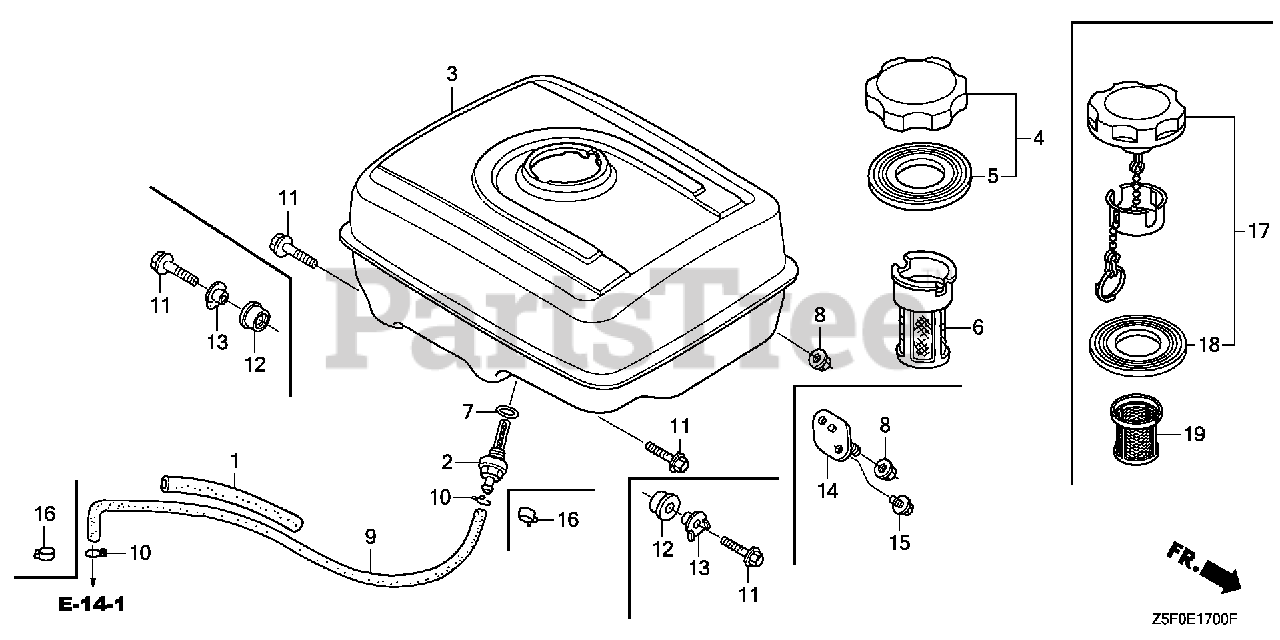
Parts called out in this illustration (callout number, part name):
1	RUBBER, SUPPORTER (107MM)
2	JOINT, FUEL TANK
3	TANK, FUEL *NH1* (BLACK)
7	O-RING (14MM) (ARAI) Use up to Engine SN 2949254.
7	O-RING (14MM) (NOK)
8	NUT, FLANGE (8MM)
9	TUBE, FUEL (4.5X210) (FKM)
11	BOLT, FLANGE (8X25)
16	CLIP, TUBE (D8)
17	CAP, FUEL FILLER
18	GASKET, FUEL FILLER CAP
19	FILTER, FUEL (FROM 1204807)
